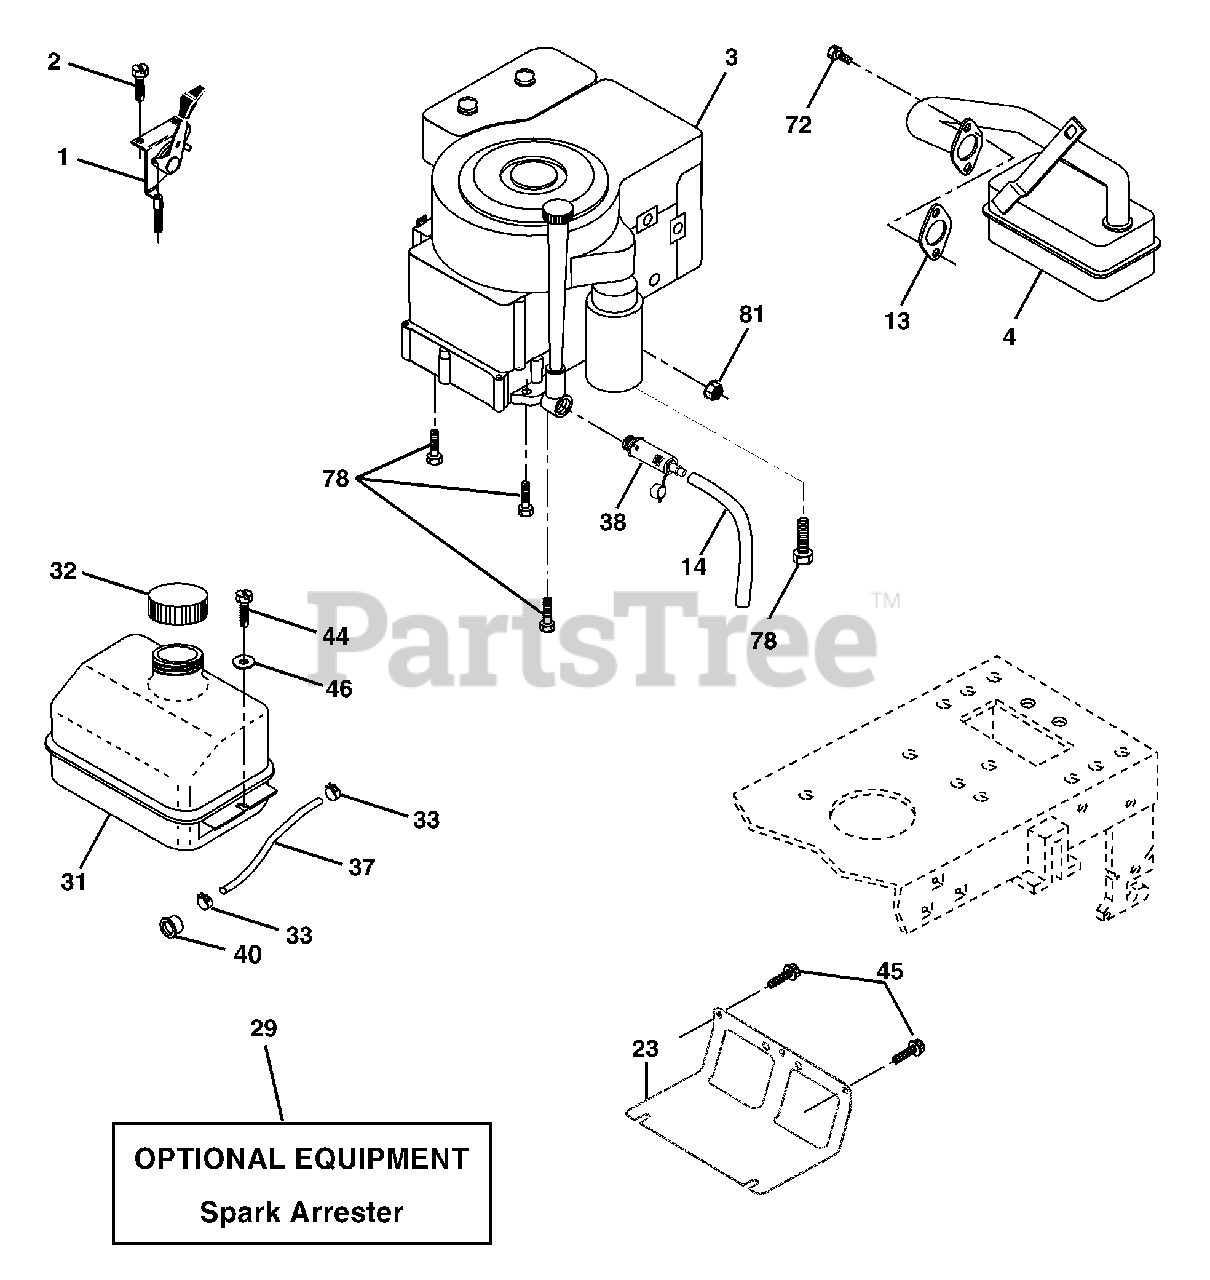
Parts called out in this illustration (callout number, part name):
1	Control, Throttle
2	Screw, Hex Head, Thread Cutting 1/4-20 x 1/2
4	Muffler
13	Gasket
14	Tube Drain Oil Easy
23	Shield Brn/Dbr Guard
29	Arrestor, Spark
31	Tank, Fuel
32	Cap Assembly, Fuel
33	Clamp, Hose
37	Line, Fuel
38	Plug Drain Oil Easy
40	Bushing, Snap, Fuel Line
44	Screw, Hex Washer Head, Thd., Roll. 1/4-20 x 3/4
45	Screw Hxwsh Thdr 3/8-16 x 3/4
46	Washer 9/32 x 7/8 x 16 Ga
72	Screw Socket Head 5/16-18 x 1
78	Screw 3/8-16 x 1-1/4
81	Nut Keps Hex 1/4-20 Unc
